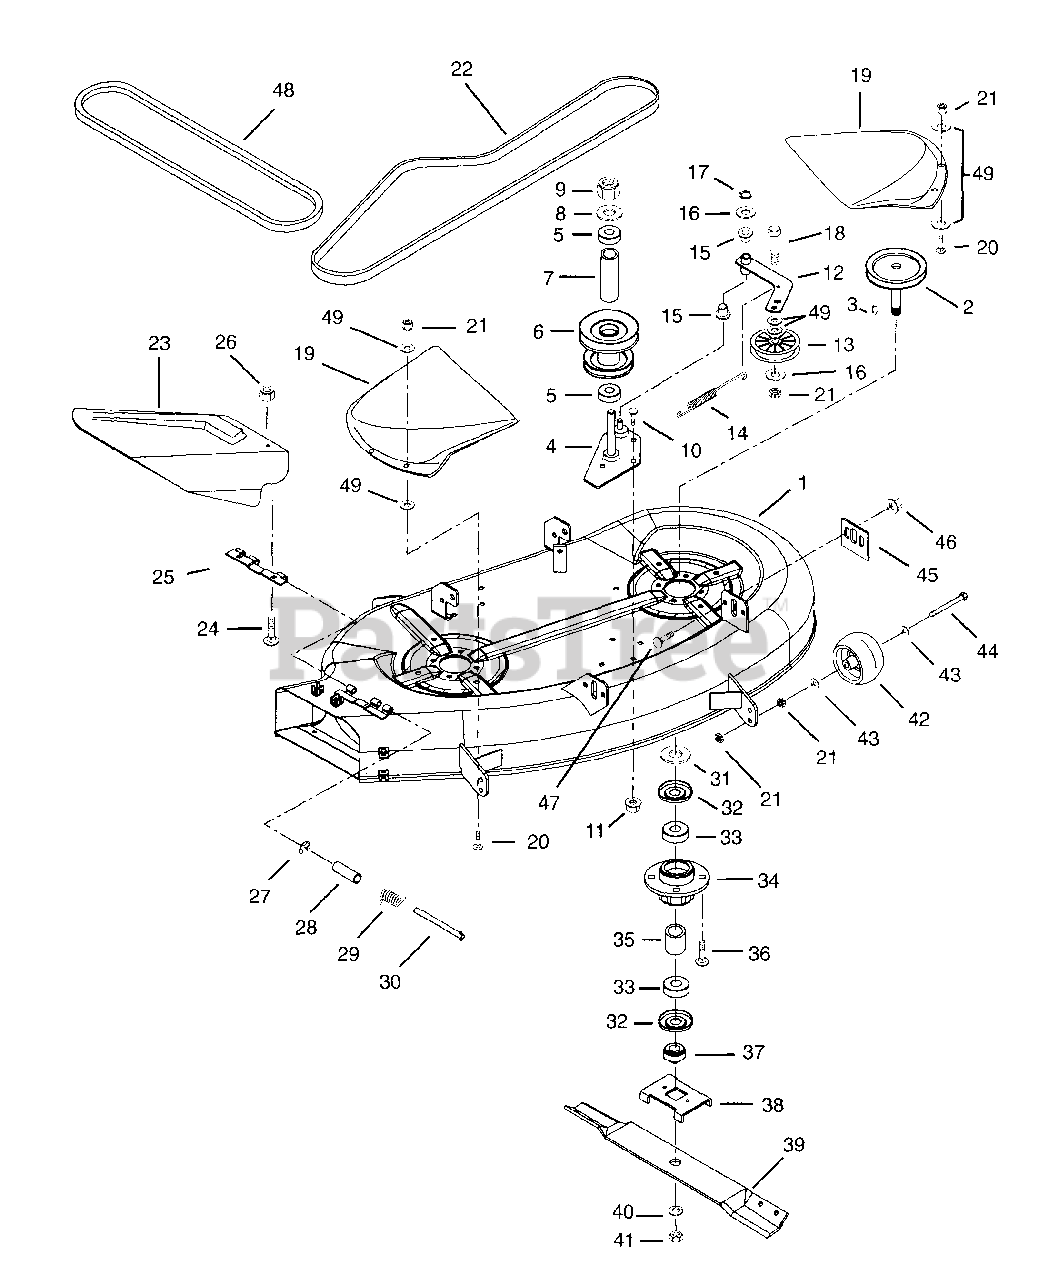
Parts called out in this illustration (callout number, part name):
1	40" MOWER DECK W/DECALS
1	40" MOWER DECK ASSY COMPLETE
2	SPINDLE, 40"
3	KEY-WDRF .188X.625X.31 SAE9MOD
4	MOUNT PLATE 40"
5	BRG-BALL .625X1.375X.44
6	JACKSHAFT PULLEY
7	SPACER .640X.880X2.545
8	WSHR-FL-STL .630X1.005X.062 YZ
9	@NUT-LK-NYL .625-18 YWZC
10	@BLT-RHDSSQNK .31-18X.62 G5YZ
11	@NUT-SPNLK-FLG .312-18 YWZC
12	IDLER ARM
13	IDLER 3.5" DIA
14	SG-TENS .113X.812X7.00
15	BSHG-FLG.500X.625X.312X.750NY
16	WSHR-FL-STL .505X.880X.072 YWZ
17	RG-RTNG-EXT .500X.042 (E)
18	@BLT-HEX .38-16X1.75 GR5 YWZC
20	@BLT-HEX .38-16X1.00 GR5 YWZC
21	@NUT-LK-CTR .38-16 YWZC
22	V-BELT, HA-RAW EDGE
23	40IN. CHUTE DEFLECTOR
24	BLT-RDHDSQSHNK.25-20X.50 YWZC
25	HINGE PLATE
26	@NUT-SPNLK-FLG .25-20 YWZC
27	RG-RTNG-EXT .312X.025
28	BSHG-SLV .334 X .502 X 1.437
29	SG-TORS .095X.50X 1.0
31	WSHR-FL-STL .755X1.25X.125 YZ
32	BEARING SLINGER
33	BRG-BALL .750X1.781X.61
34	SPINDLE HOUSING
35	SPACER .753X1.000X1.140
36	@BLT-RDHDSQNK .38-16X1.00 G2YZ
37	RETAINER HUB
38	BLADE TRAY 48
39	BLADE
39	MULCHING BLADE
40	@WSHR-LK .75X.188 REG YWZC
41	NUT-JAM .75-10 YWZC
43	@WSHR-FL-STL.38X.875X.083 YWZC
44	@BLT-HEX .38-16X3.50 GR5 YWZC
45	MOWER ADJUSTMENT TAB
46	@NUT-SPNLK-FLG .312-18 YWZC
47	BLT-RDHDSQSHK.31-18X.75 GR2 YW
48	V-BELT, HA-WRAPPED
49	@WSHR-FL-STL.406X.812X.065 YWZ
